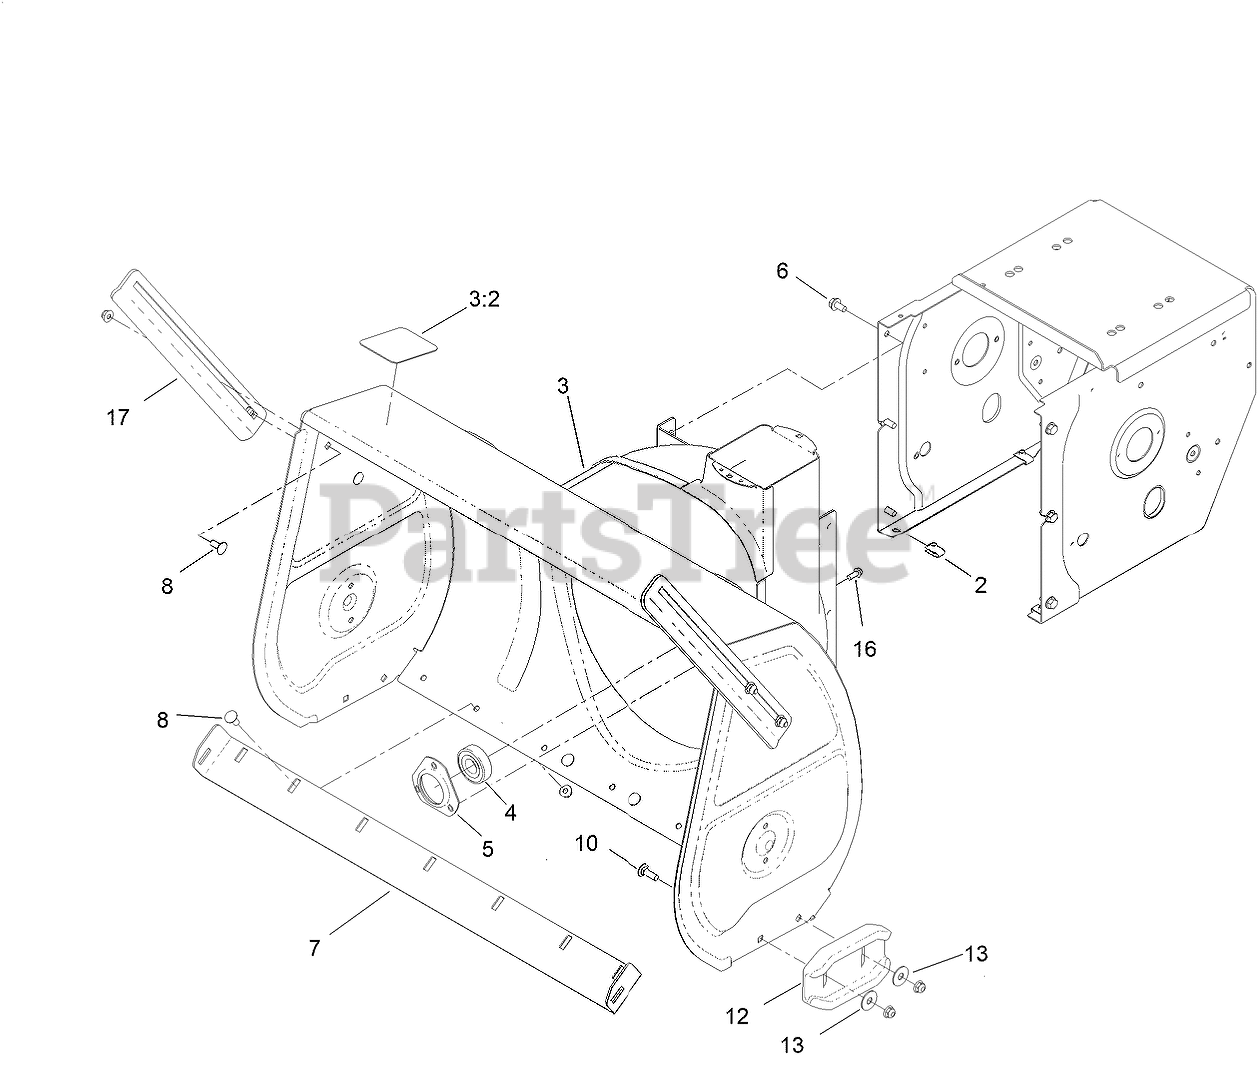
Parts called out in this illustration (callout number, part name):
3	AUGER HOUSING ASM
3:2	DECAL-DANGER, AUGER
4	BEARING-BALL
5	RETAINER-BEARING
6	SCREW-HWHTF
7	BLADE-SCRAPER
8	BOLT-CARR
10	BOLT-CARR
12	SKID-CAST
13	WASHER-FLAT
16	SCREW-HWH
17	BREAKER-DRIFT, SIDE
